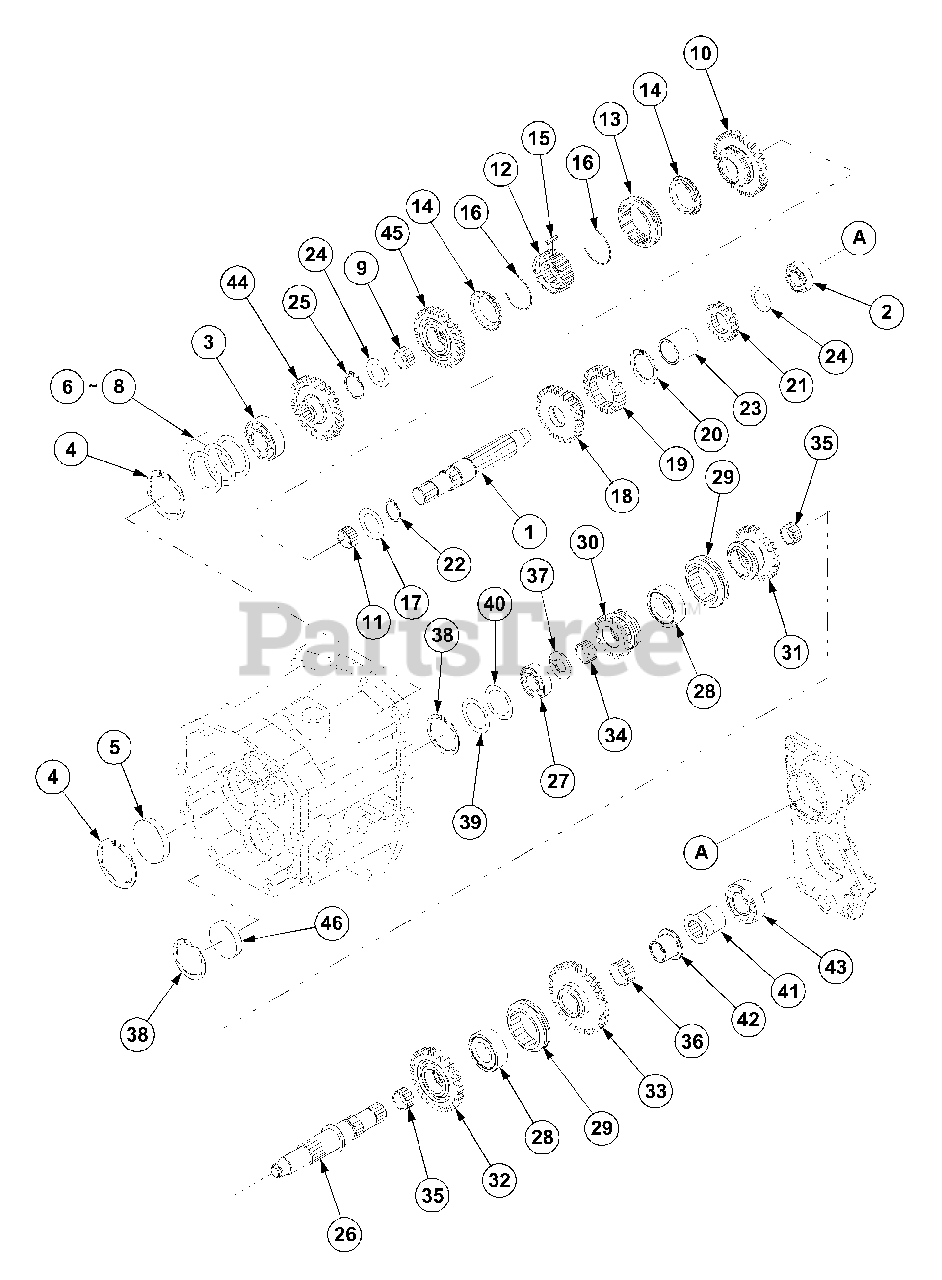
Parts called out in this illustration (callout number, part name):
9	Bearing,Needle
11	Bearing,Needle
12	Hub,Synchronize
13	Sleeve,Synchronize
14	Ring,Synchroniz
15	Key,Synchronize
16	Spring,Synchronize
22	C-Ring
24	Liner,Thrust
25	C-Ring
34	Bearing,Needle
35	Bearing,Needle
36	Bearing,Needle
38	C-Ring
